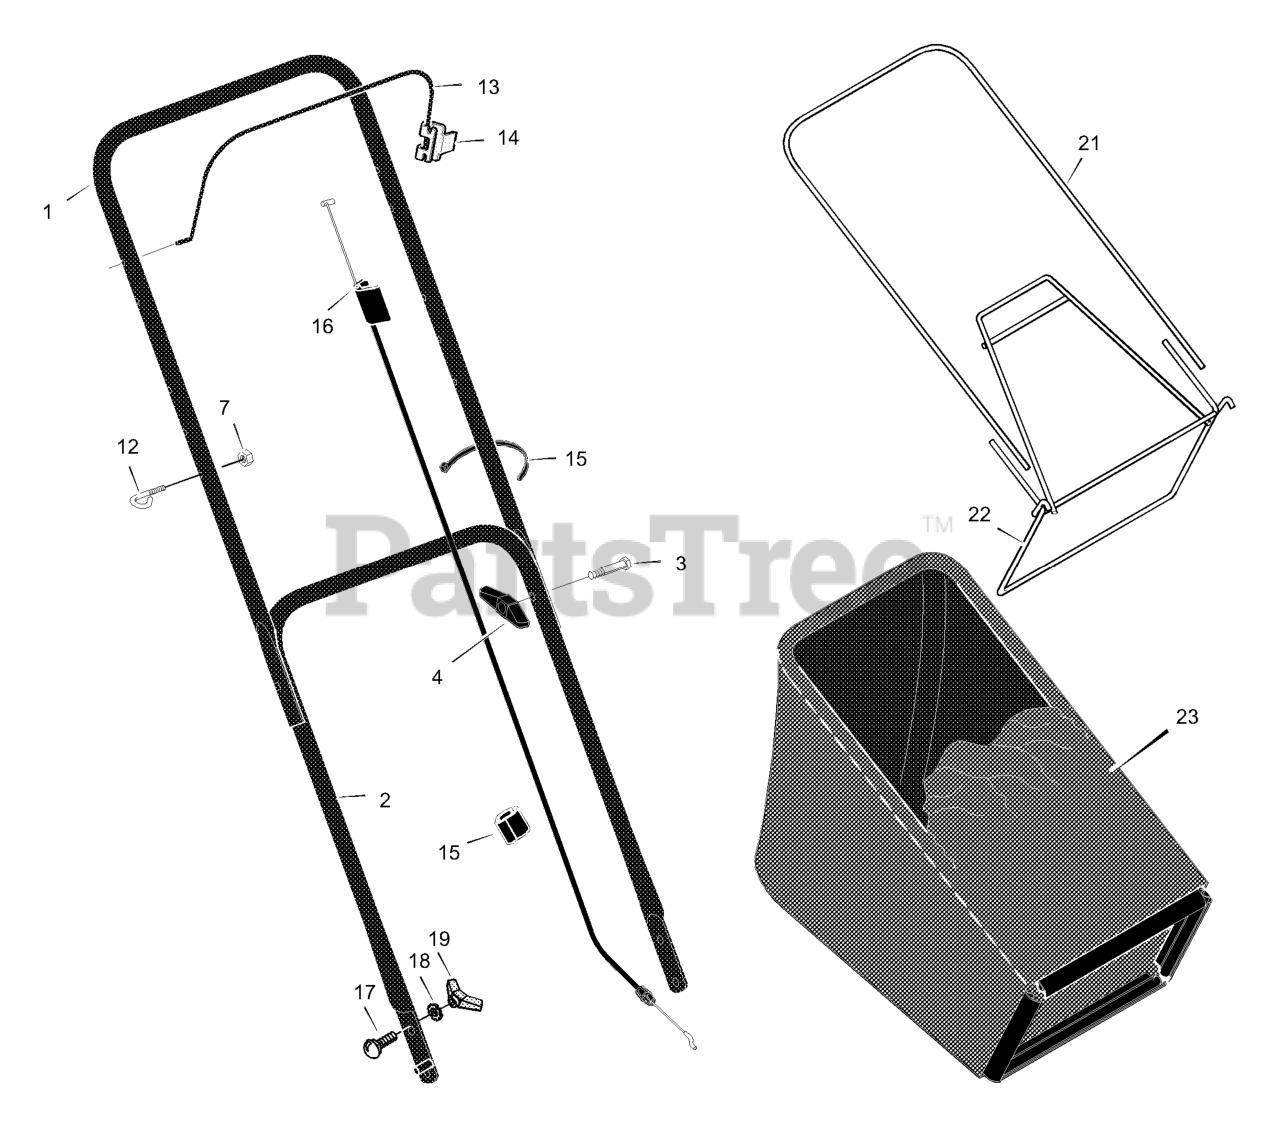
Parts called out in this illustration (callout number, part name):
1	Handle, Upper (Black)
2	Handle, Lower (Black)
4	Knob, Plastic
7	Locknut
12	Guide, Rope
13	Engine Stop Lever
14	Bracket, Stop Lever
15	Clip, Cable
16	Engine Stop Cable
17	Bolt, Carriage
19	Knob, Plastic
21	Frame, Top
22	Frame Assembly
23	Bag, Cloth
